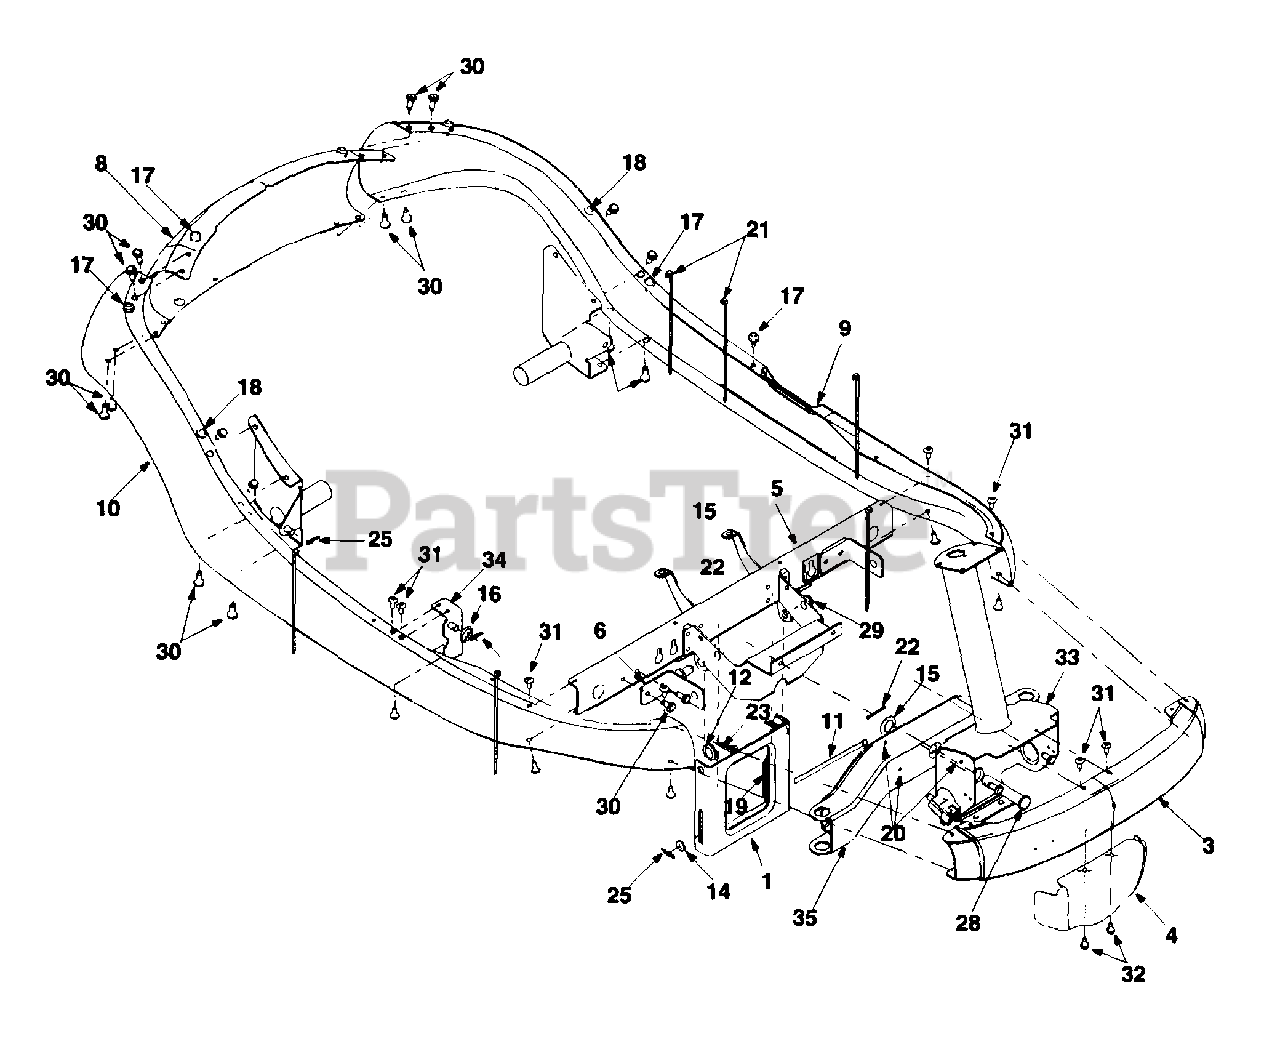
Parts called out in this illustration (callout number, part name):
12	Flat Washer .531 X 1.062 X .134
14	Flat Washer 5/16
15	Flat Washer .64 I.D. X 1.24 X .06
16	Flat Washer 3/8 X 1.00 X .030
17	Rubber Bumper
18	Rubber Bumper
19	Extension Spring
21	Cable Tie
22	Hairpin Clip
23	Hairpin Clip
25	Hairpin Clip
28	Clevis Pin
29	Lift Bracket Pin
30	TT Screw 5/16-18 x .75
31	Torx Mach. AB Scr. 1/4-14 x 0.625"
32	Hex TT Screw 1/4-20
33	Steering Support Bracket
34	Pivot Bracket Ass'y.: Hood
